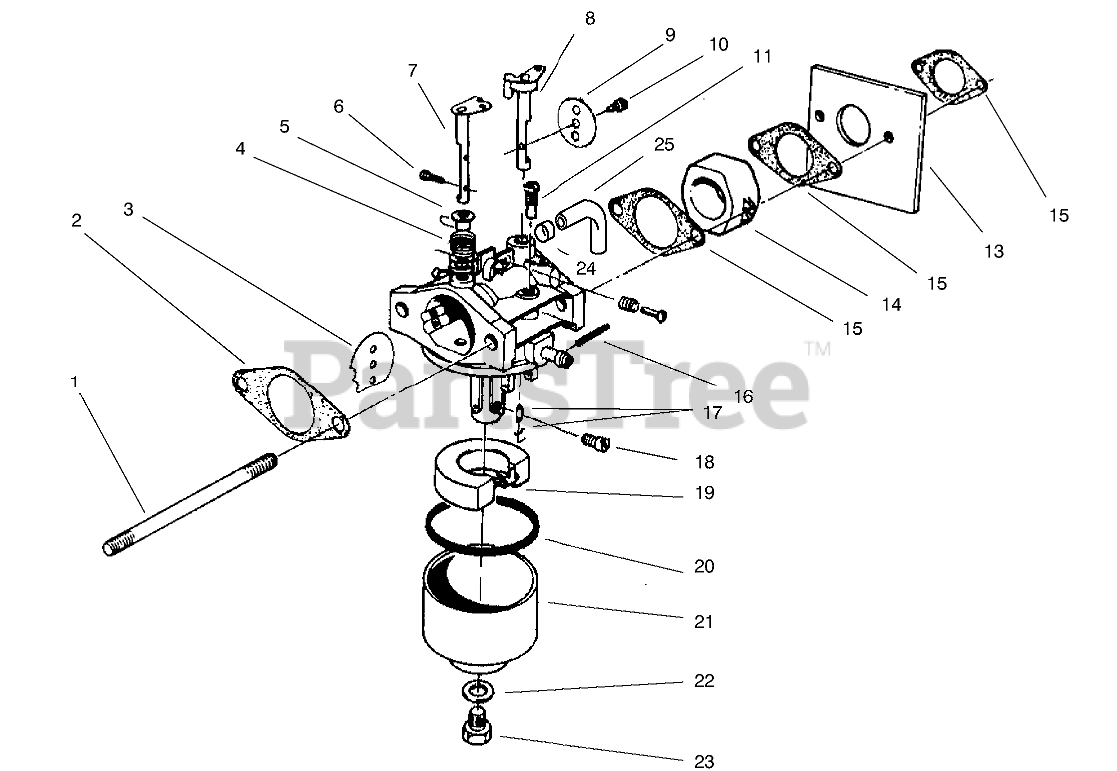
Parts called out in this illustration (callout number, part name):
1	STUD-CARBURETOR
2	GASKET-AIR CLEANER
3	PLATE
4	SPRING
5	BUSHING
6	SCREW
7	SHAFT-CHOKE
8	SHAFT
9	PLATE
10	Screw-Throttle
11	PILOT JET
11	JET-PILOT
13	SHIELD-CARBURETOR
14	INSULATOR-CARBURETOR
15	GASKET-CARB
16	Pin
17	NEEDLE
18	MAIN JET (76.3)
19	FLOAT
20	GASKET
21	BOWL - FLOAT
22	GASKET
23	SCREW
24	CLAMP
25	VENT TUBE
